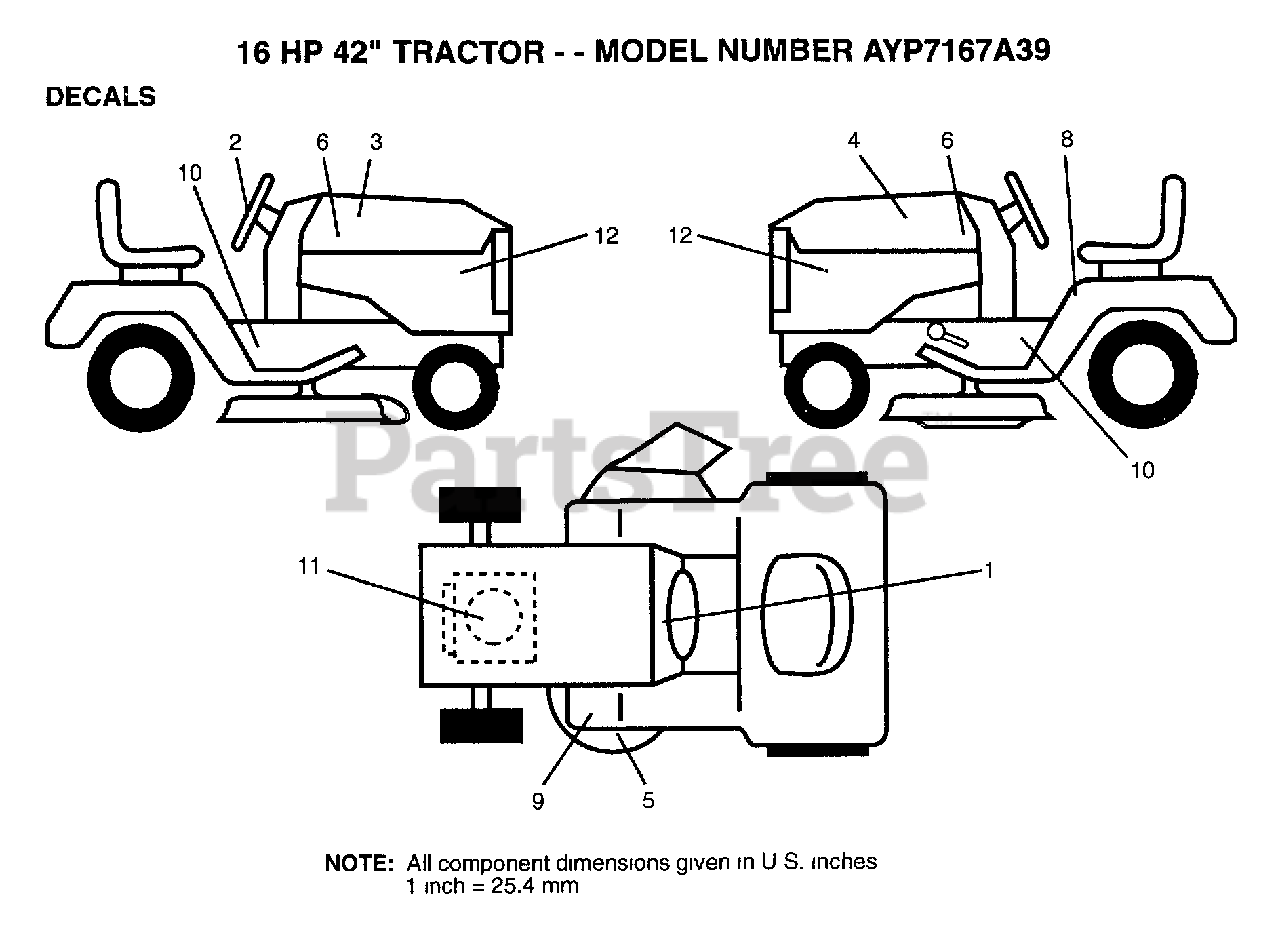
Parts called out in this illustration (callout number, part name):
5	DECAL.DECK.MULCH
8	DECAL
11	DECAL.ENG.805720
